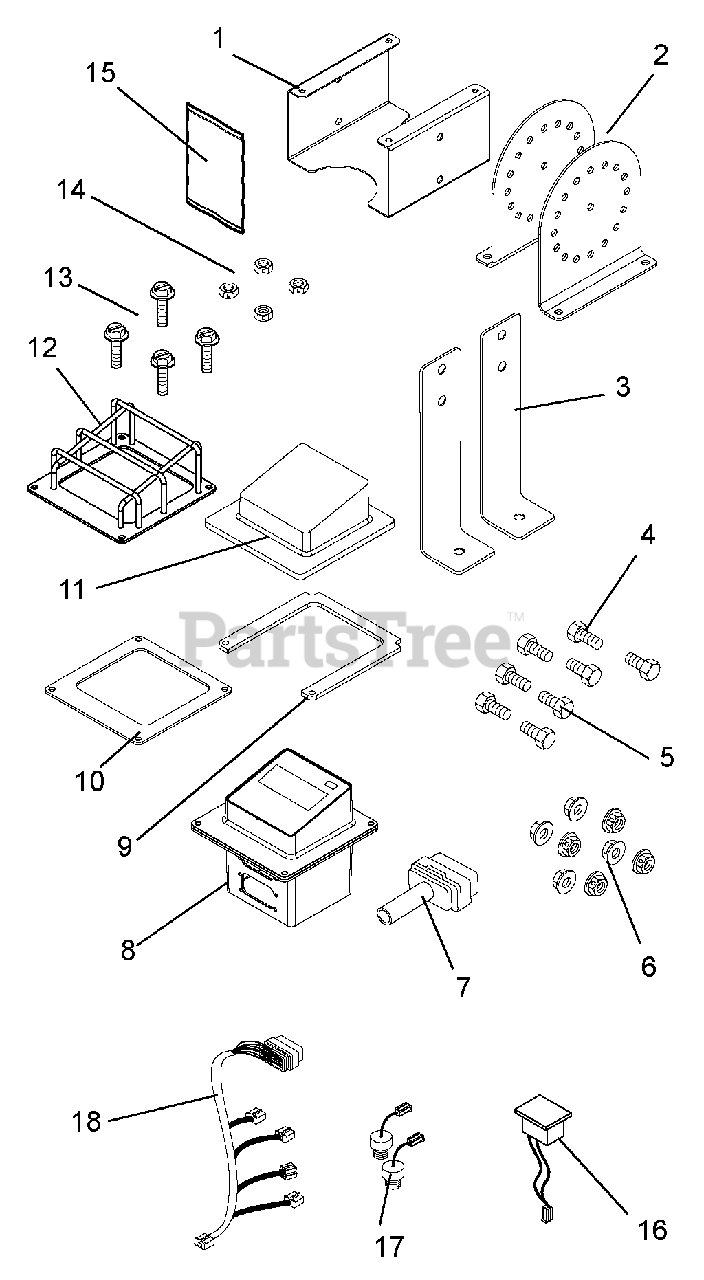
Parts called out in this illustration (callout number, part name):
1	BRKT, EYE-Q RETRO FIT
2	LEG, EYE-Q RETRO FIT
3	LEG, LONG EYE-Q
4	@BLT-HEX .25-20X1.00 GR5 YWZC
5	@BLT-HEX .25-20X.50 GR5 YWZC
6	@NUT-LK-TOP-FLG .25-20 YWZC
7	HARNESS,EYE-Q RETRO FIT CONN.
8	EYE Q ENHANCED
9	SPACER, ENCLOSURE MTG. (BTM)
10	GASKET-EYE Q
11	GUARD, ELEMENT
12	WMT, EYE-Q GUARD (BLACK)
13	@SCR-MCH 10-24X1.50 HWH YWZC
14	@NUT-LK-NYL 10-24 W/INSRT YWZC
15	MANUAL-ENHANCED EYE Q
15	MANUAL, EYE-Q 2006 TRANSLATED
16	KIT,EYE-Q ACCELEROMETER
17	KIT,EYE-Q TEMPERATURE
18	KIT,EYE-Q ACCESORY WIRE HRNS.
